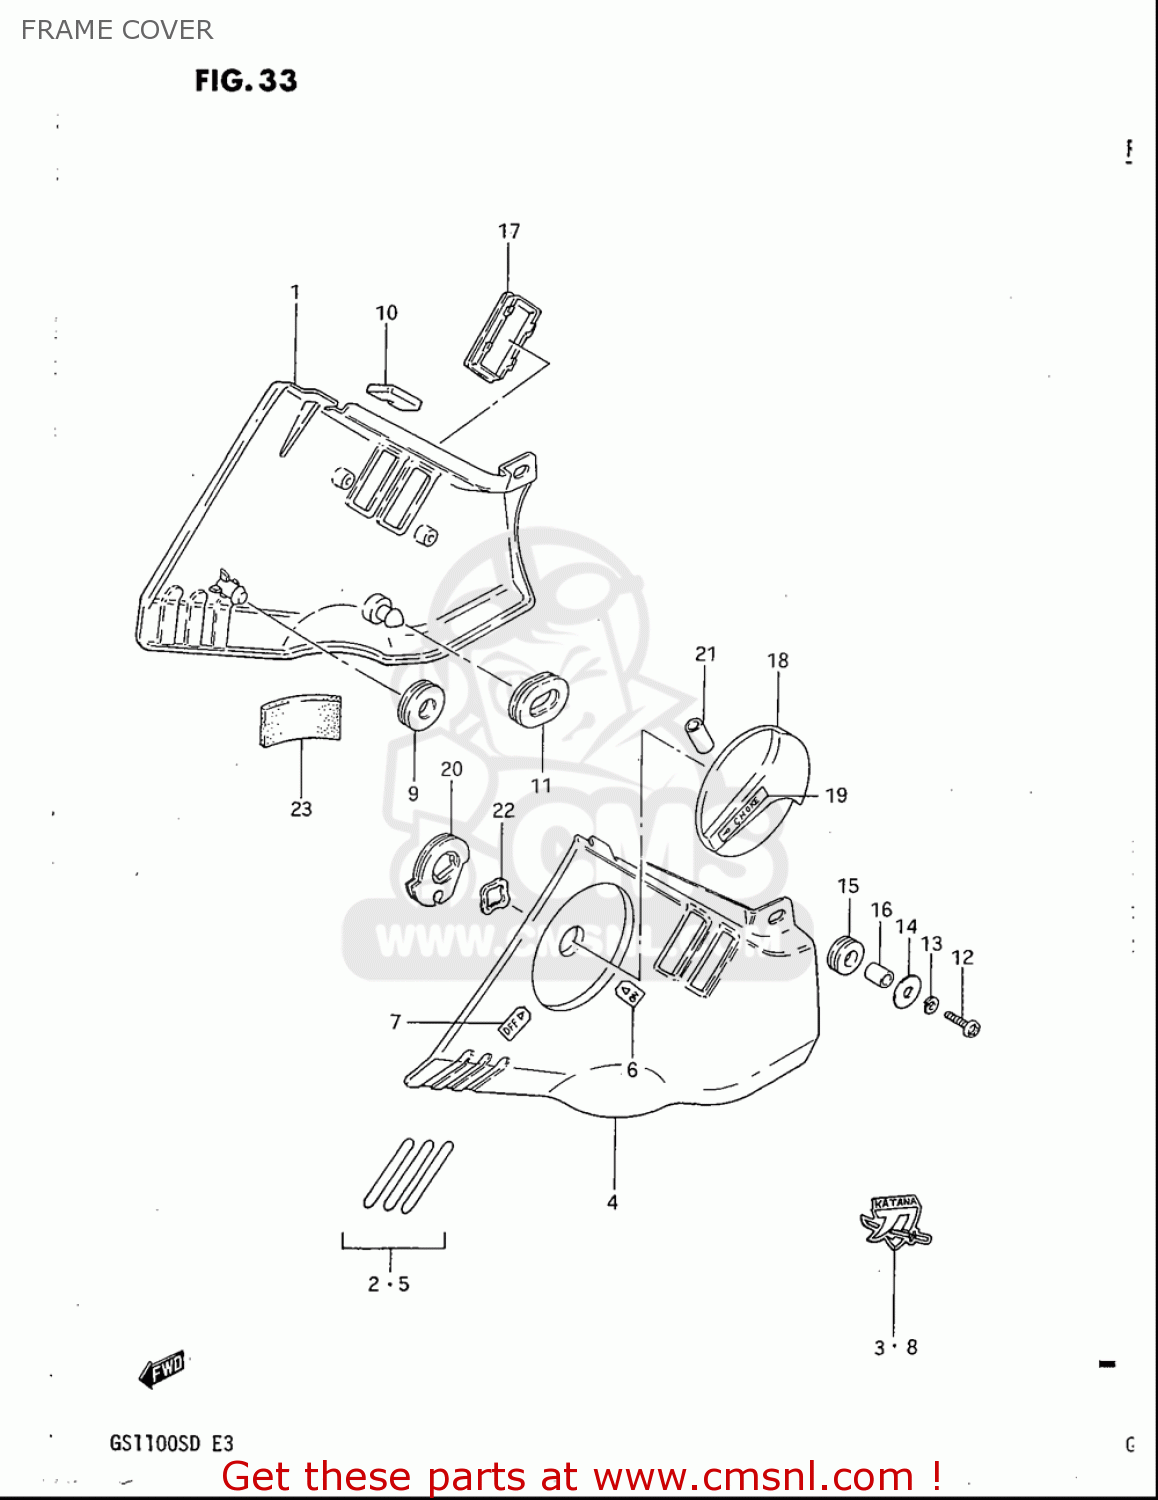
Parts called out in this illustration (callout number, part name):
1	COVER SET,FRAME,R(SILVER)
2	LABEL,FRAME COVER DENT,R
3	EMBLEM,FRAME COVER
4	COVER SET,FRAME,L(SILVER)
5	LABEL,FRAME COVER DENT,L
6	LABEL,CHOKE ON
7	LABEL,CHOKE OFF
8	EMBLEM,FRAME COVER
9	CUSHION
10	CUSHION
11	CUSHION
12	SCREW
13	WASHER,LOCK
14	WASHER(6.5X20X1.6)
15	CUSHION
16	SPACER(6.1X9X7.5)
17	CAP,FRAME COVER SWITCH HOLE
18	LEVER,CHOKE CABLE
19	LABEL,CHOKE LEVER
20	HOLDER,STARTER CABLE
21	TUBE,CHOKE CABLE LEVER
22	WASHER
23	PAD
